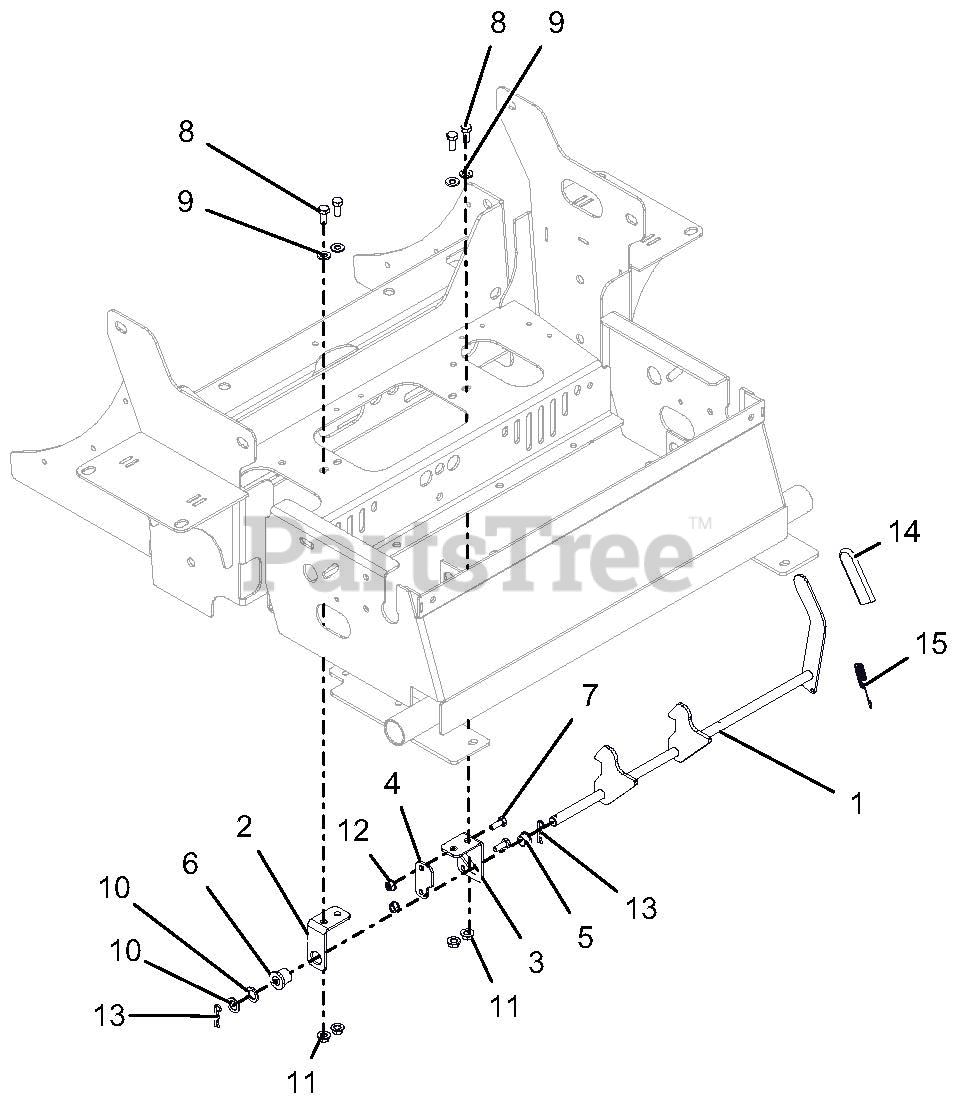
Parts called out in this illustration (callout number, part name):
1	WMT, SEAT LATCH
2	MOUNT, SEAT LATCH - RH
3	MOUNT, SEAT LATCH - LH
4	RETAINER-SEAT LATCH
5	BUSHING, POLYLINER - .50 SPLIT
6	BSHG, FLANGE .515 X .750 X .745 X 1.00 NYLON
7	BLT-HEX .25-20X.75 GR5 YWZC
8	BLT-HEX .31-18X.75 GR5 YWZC
9	WSHR-FL-STL.344X.688X.065YWZC
10	WSHR-FL-STL .520X.827X.062 YWZC
11	NUT, LK-TOP-FLG .312-18 YWZC
12	NUT, LK-TOP-FLG .25-20 YWZC
13	PIN-HAIR INT .08X.38X1.42 YWZC
14	GRIP-VINYL-YELLOW .125 x 1.0 x 3.0
15	SPRG, EXTENSION
